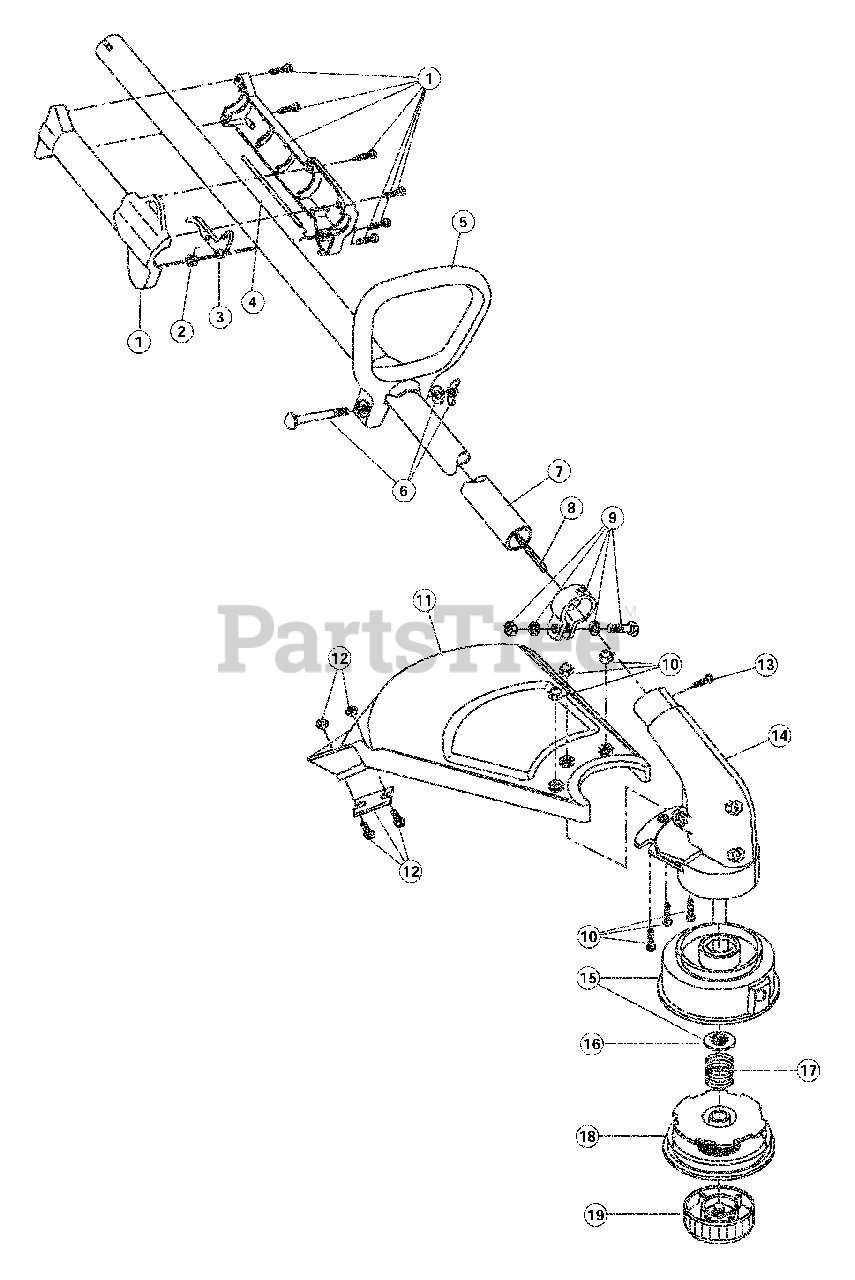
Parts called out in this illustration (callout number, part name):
1	Throttle Housing & Trigger Assembly
2	Throttle Trigger Spring
3	Throttle Trigger
4	Throttle Cable Assembly
5	D-Handle
6	D-Handle Hardware
7	Drive Shaft Housing Assembly
8	Flexible Drive Shaft
9	Lower Clamp Assembly
10	Guard Mounting Screw Assembly
11	Guard and Blade Assembly
12	Blade Assembly
13	Anti-Rotation Screw
14	Gearbox Assembly
15	Outer Spool and Eyelet Assembly
16	Retainer
17	Spring
18	Inner Reel
19	Bump Head Knob Assembly
